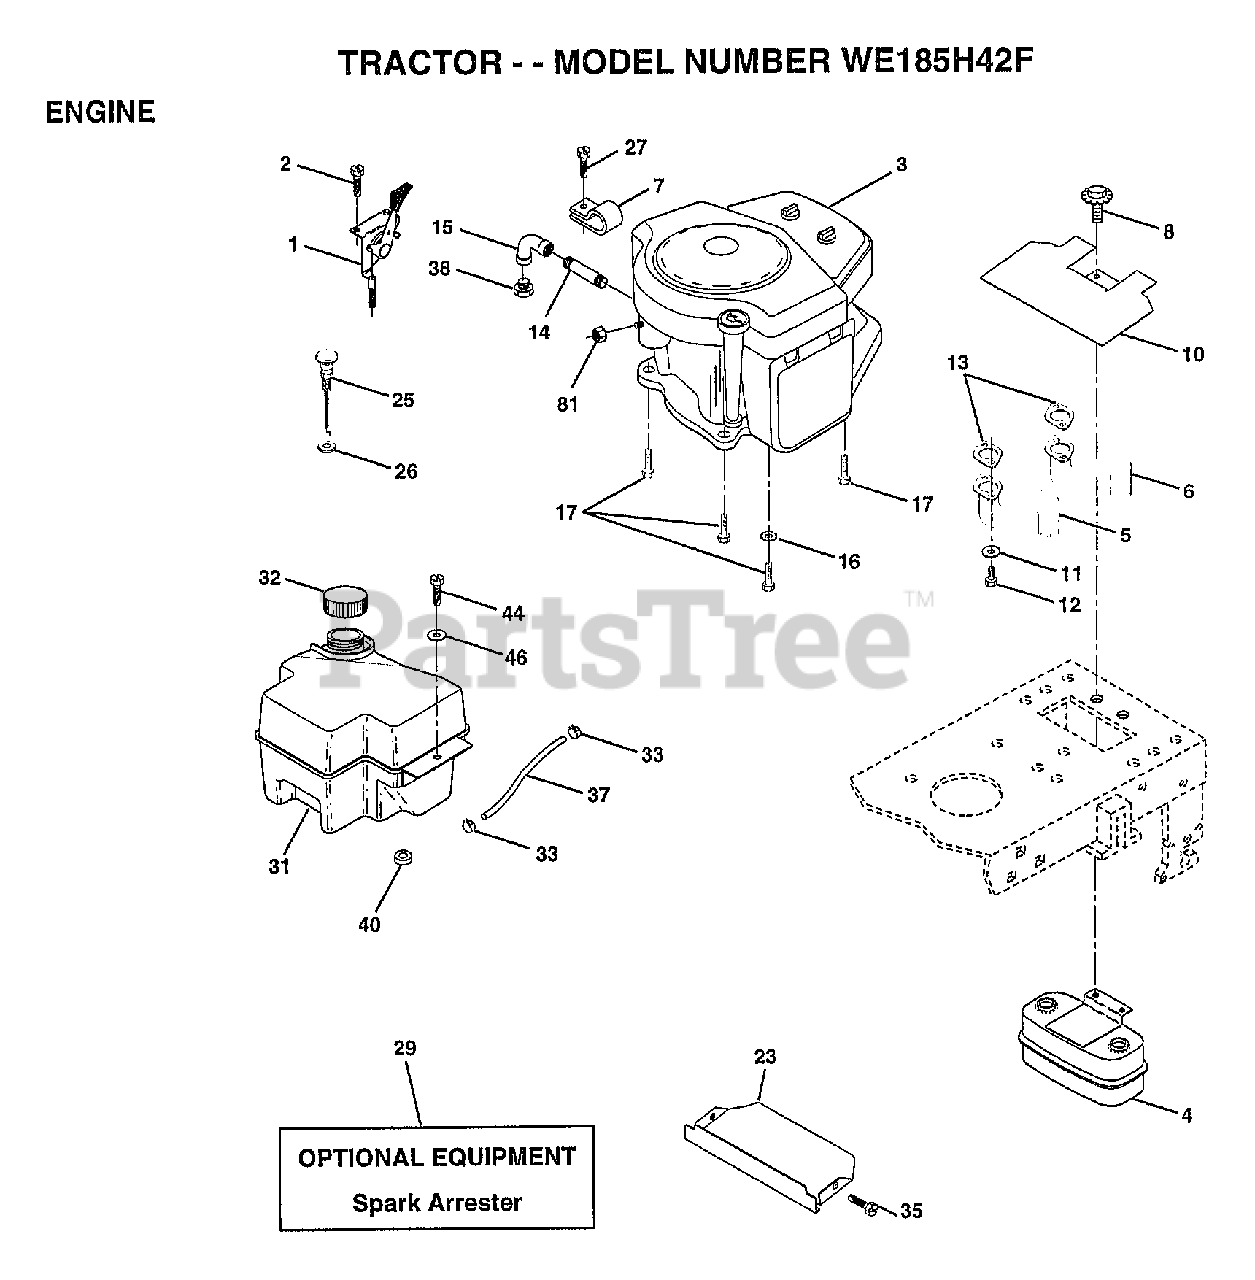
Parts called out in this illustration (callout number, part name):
1	CONTROL THRT 35.5
2	SCREW LT
4	MUFFLER.TW.LOTONE
5	EXHAUST.B&S.18.LH
6	EXHAUST.B&S.18.RH
7	CLAMP.TUBE.DBL.EN
8	BOLT.5/16-18.UNC
10	SHIELD.HEAT.
11	LOCKWASHER
13	GASKET MUFFLER
14	PIPE NIPPLE LT
15	ELBOW
16	LOCKWASHER
17	SCREW LT
23	SHIELD.BRN/DBR.GD
25	CONTROL.CHOKE.37
26	"NUT,KEPS 3/8-24IM"
27	"SCREW-TT,10-32 FL"
31	TANK.FUEL.FRONT.
32	CAP ASM FUEL
33	HOSE CLAMP
35	SCREW
37	LINE FUEL
44	SCREW HEX CRT
46	WASHER
81	NUT
